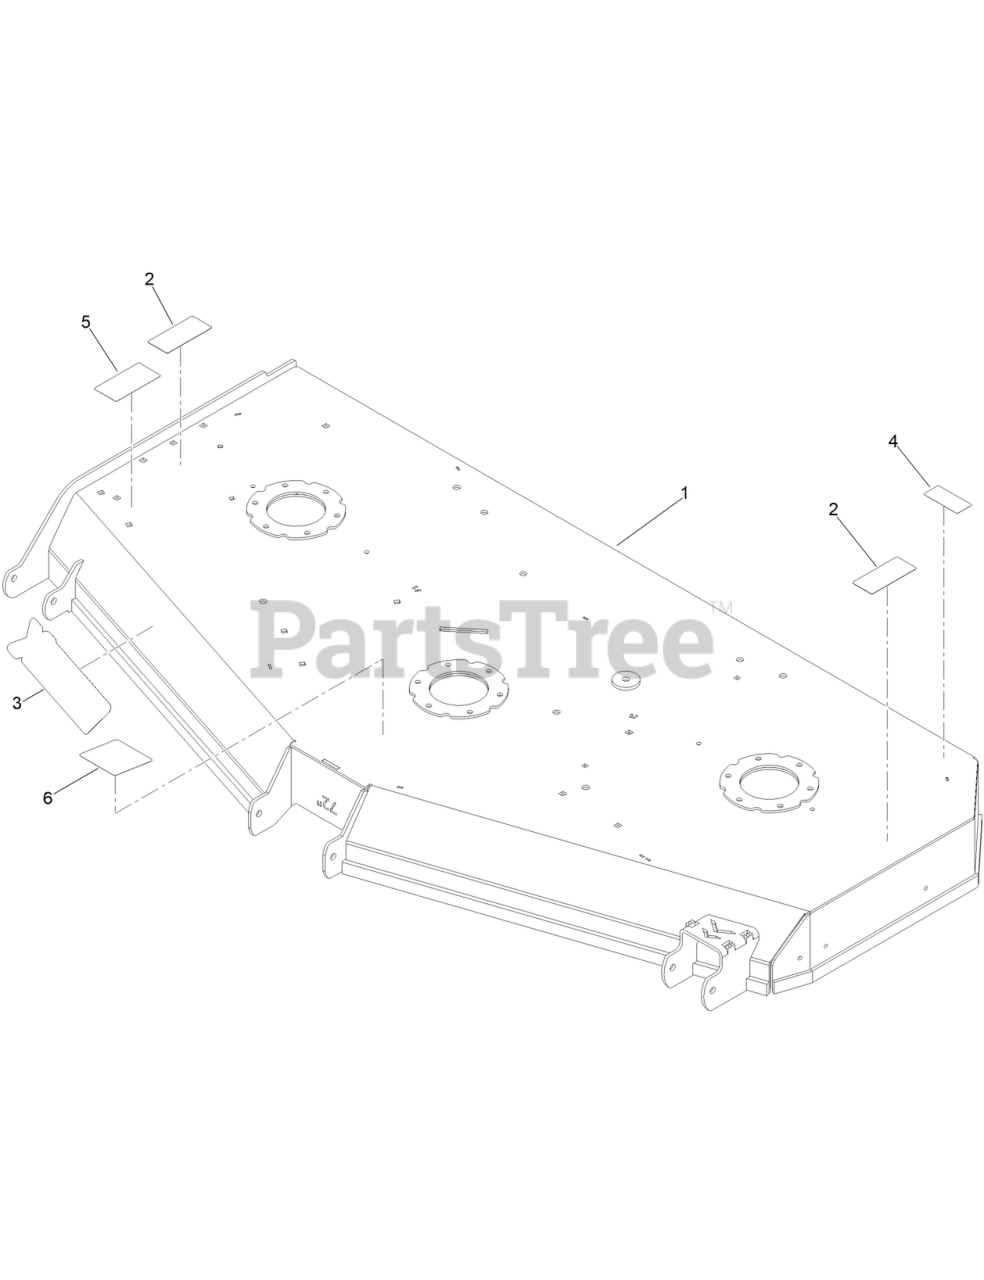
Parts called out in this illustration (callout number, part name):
1	72IN MWR DECK ASSY PAINTED BLACK
2	DECAL-ROTATING FAN HAZARD
3	DECAL-DECK, 72-XFT
4	DECAL-SAFETY BLADE TORQUE
5	DECAL-DANGER, DECK
6	DECAL-DECK BELT ROUTING
